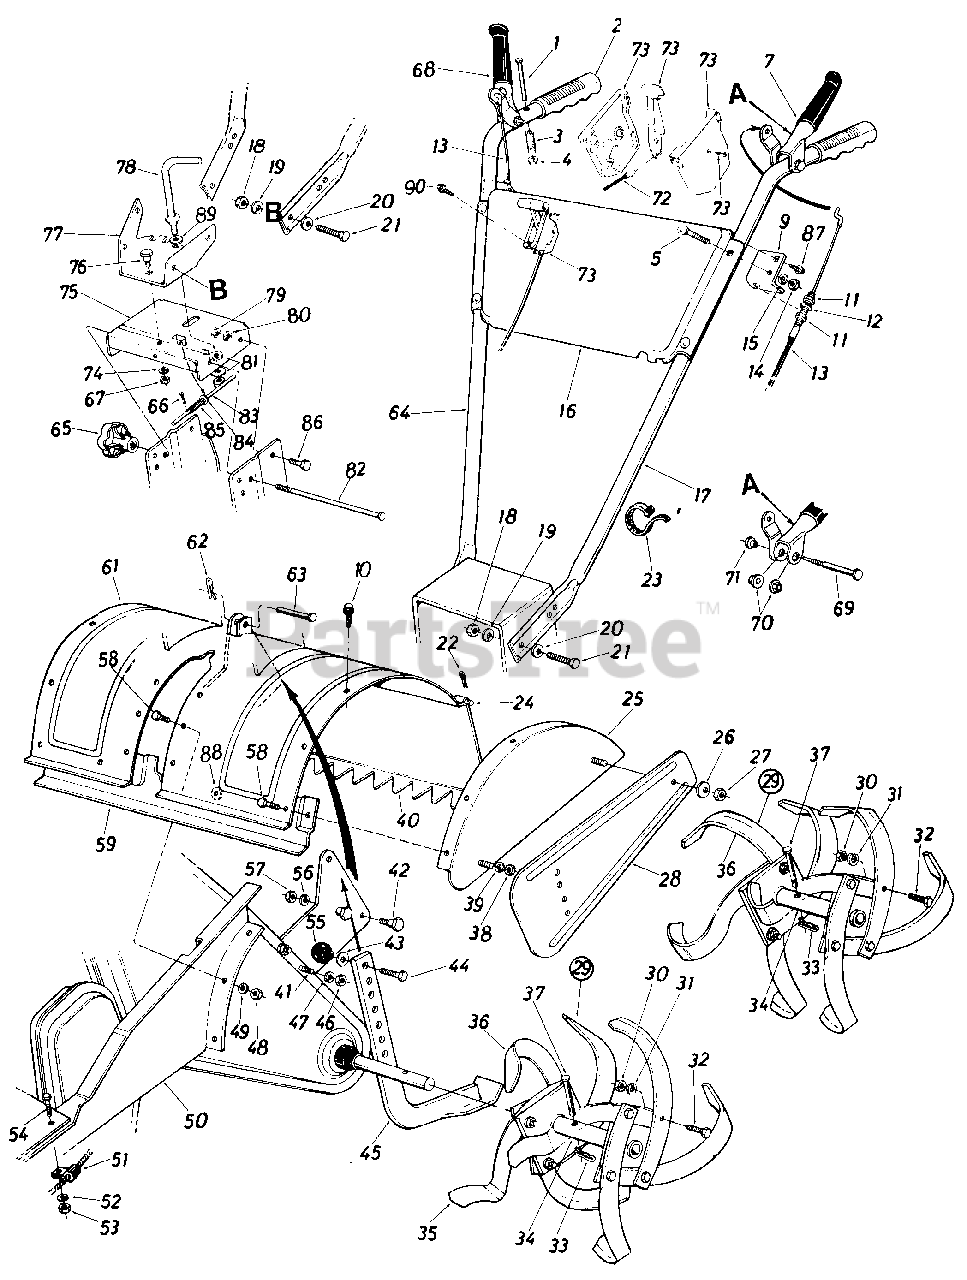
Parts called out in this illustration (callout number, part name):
1	Clevis Pin 1/4" Dia. x 2.25"
2	Grip
3	Compression Spring .33"O.D. x 1.2" Lg.
4	Cap Speed Nut 1/4" Rod
5	Carr. Bolt 5/16-18 x 1.75"
7	Clutch Grip Ass'y.-L.H.
9	Clutch Cable Bracket
10	Hex Wash. S-Tap Scr. 5/16-18 x.62" Lg.
11	Hex Nut 5/16-24 Thd.
12	L-Wash. 5/16" I.D.
13	Clutch Control Cable
14	Hex Nut 5/16-18 Thd.
15	L-Wash. 5/16" I.D.
16	Handle Panel
17	Handle-L.H.
18	Hex Nut 3/8-16 Thd.
19	L-Wash. 3/8" I.D.*
20	Bell-Wash. 3/8" I.D.
21	Hex Bolt 3/8-16 x 1.00" Lg.
22	Cotter Pin 3132" Dia. x 314"
23	Cable Tie
24	Tiller Flap Rod
27	Hex Nut 5/16-18 Thd.
30	Hex Nut 3/8-24 Thd.
31	L-Wash. 3/8" I.D.
32	Hex Bolt 3/8-24 x 1.25" Lg.
33	Hairpin Cotter
38	Hex Nut 5/16-18 Thd.*
39	L-Wash. 5/16" I.D.
41	Hex Bolt 5/16-18 x 1.0" Lg.
42	Shld. Bolt 1/2" Dia. x .426"
43	Fl-Wash. 3/8" I.D. x 518" O.D.
44	Hex Bolt 3/8-16 x 314" Lg.*
46	Hex Nut 5/16-18 Thd.
47	L-Wash. 5/16" I.D.
48	Hex Nut 5/16-18 Thd.
49	L-Wash. 5/16" I.D.
52	L-Wash. 5/16" I.D.
53	Hex Nut 5/16-18 Thd.
54	Hex Bolt 5/16-18 x 314" Lg.
55	Ball Knob 1-1/4" Dia.
56	L-Wash. 3/8" I.D.
57	Hex Nut 3/8-16 Thd.
58	Hex Bolt 5/16-18 x .75" Lg.
62	Hairpin Cotter
63	Clevis Pin 3/8" Dia.
64	Handle-R.H.
66	Cotter Pin 1/16" Dia. x .75" Lg.
67	Hex Cent. L-Nut 3/8-16 Thd.
68	Clutch Grip Ass'y.-R.H.
69	Shoulder Bolt .38" Dia. x 1.53" Lg.
70	Hex Flange Plastic Bearing
71	Shoulder Nut 1/4-20 Thd.
72	Throttle Control Wire
73	Throttle Control Box Ass'y.
74	Bell-Wash. .40" I.D. x 1.13" O.D.
79	Hex Cent. L-Nut 3/8-16 Thd.
80	Bell-Wash. .40" I.D. x .88" O.D.
81	Bell-Wash. 1/2" I.D. x 1.00" O.D.
82	Lock Pin 5/16" Dia. x 8"
83	Lower Sliding Ass'y.
84	Fl-Wash. .291" I.D. x .62" O.D.
85	Compression Spring .36" O.D. x 1.00" Lg.
86	Shoulder Bolt 1/2" Dia. x .170" Lg.
87	Hex Wash. S-Tap Scr. 1/4-20 x.50" Lg.
88	Bell-Wash. 5/16" I.D.
89	Fl-Wash. 5/8" I.D.
90	Self-Tap Scr. #10 x 1/2" Lg.
14979-0498	Rear Tine Shield - OLD CUB YELLOW (0498)
14979-0638	SHIELD-REAR TINE - MTD/TROY-BILT RED (0638)
14979-0665	SHIELD-REAR TINE - YARDMAN GREEN (0665)
